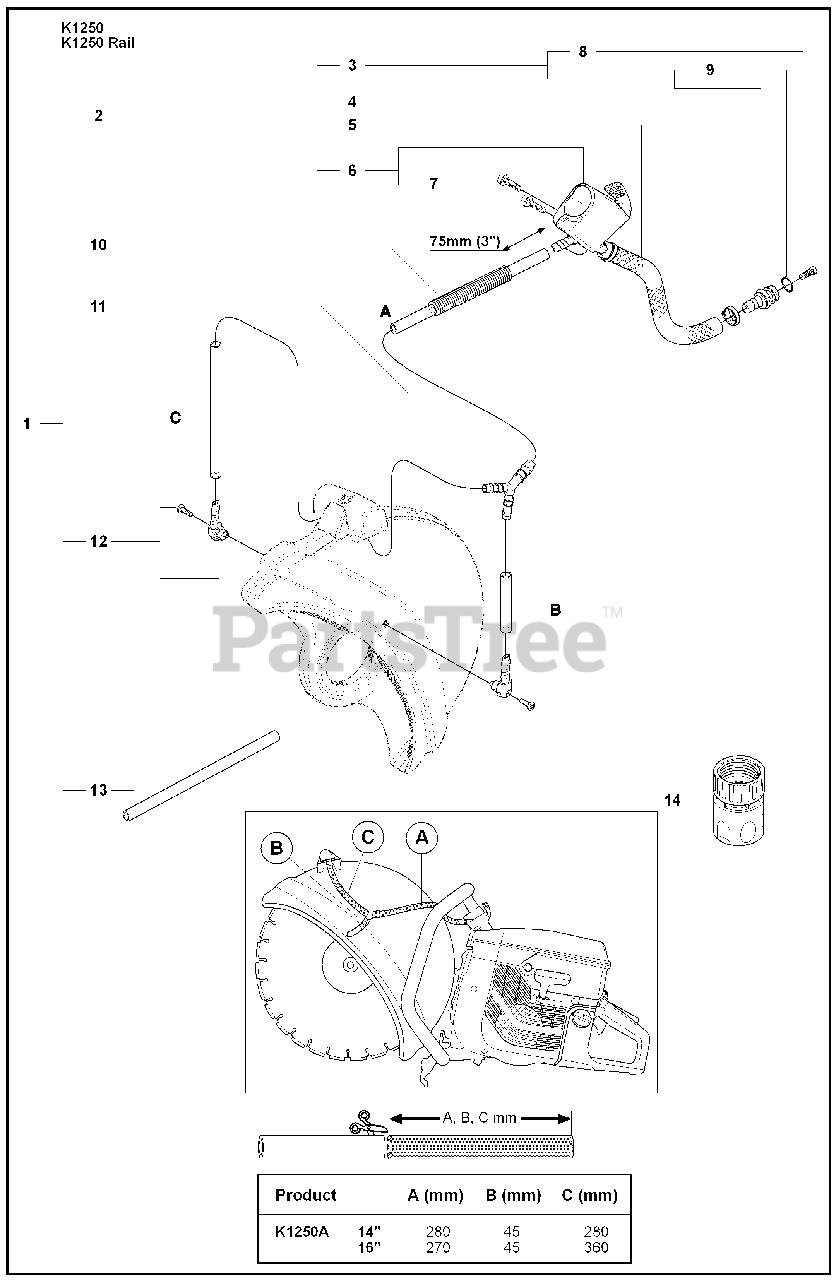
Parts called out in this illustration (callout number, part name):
1	WATER HOSE KIT
2	HOSE
3	NIPPLE
4	HOSE CLAMP
5	HOSE
6	VALVE ASSY
9	O-RING
10	PROTECTIVE SPRING
13	HOSE
14	COUPLER
